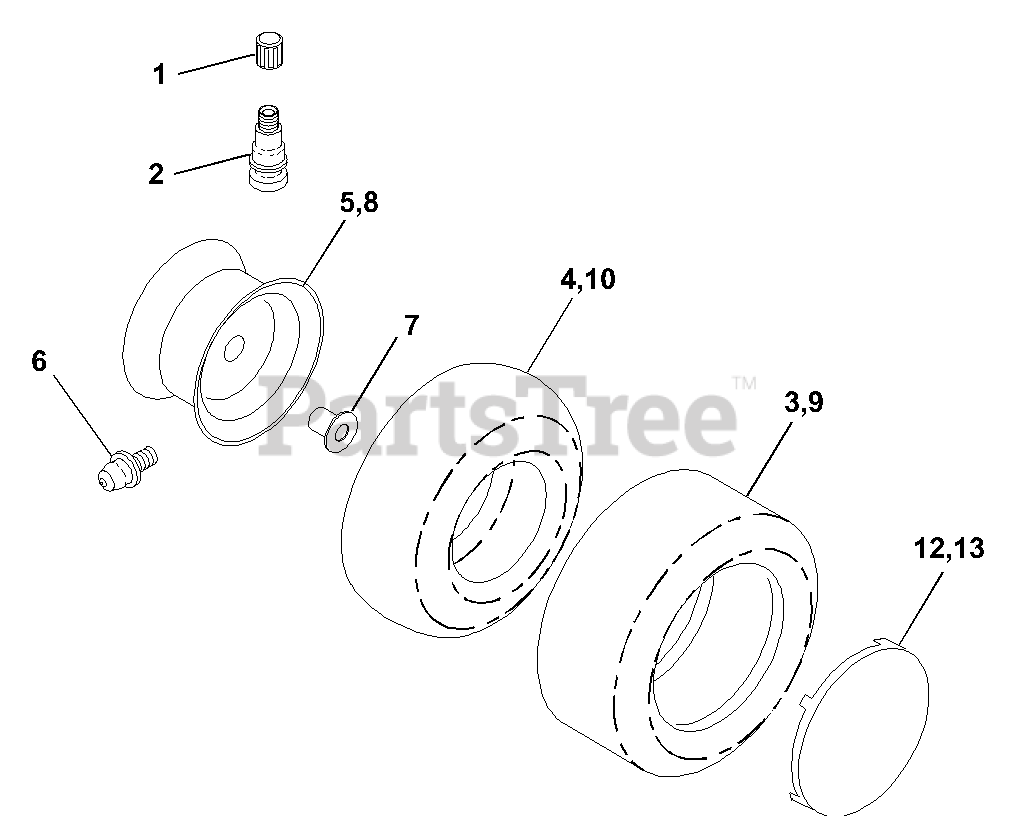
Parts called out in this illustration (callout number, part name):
1	Cap Valve Tire
2	Stem Valve
3	Tire F Ts 15 X 6 0 - 6 Service
4	Tube Front (Service Item Only)
5	Rim Asm 6" front White Service
6	Fitting Grease (Front Wheel Only)
7	Bearing Flange (Front Wheel Only)
8	Rim Asm 8"rear White Service
9	Tire R Ts 20 10 C Service
10	Tube Rear (Service Item Only)
12	Cover Wheel 6"white
13	Cover Wheel 8"white
